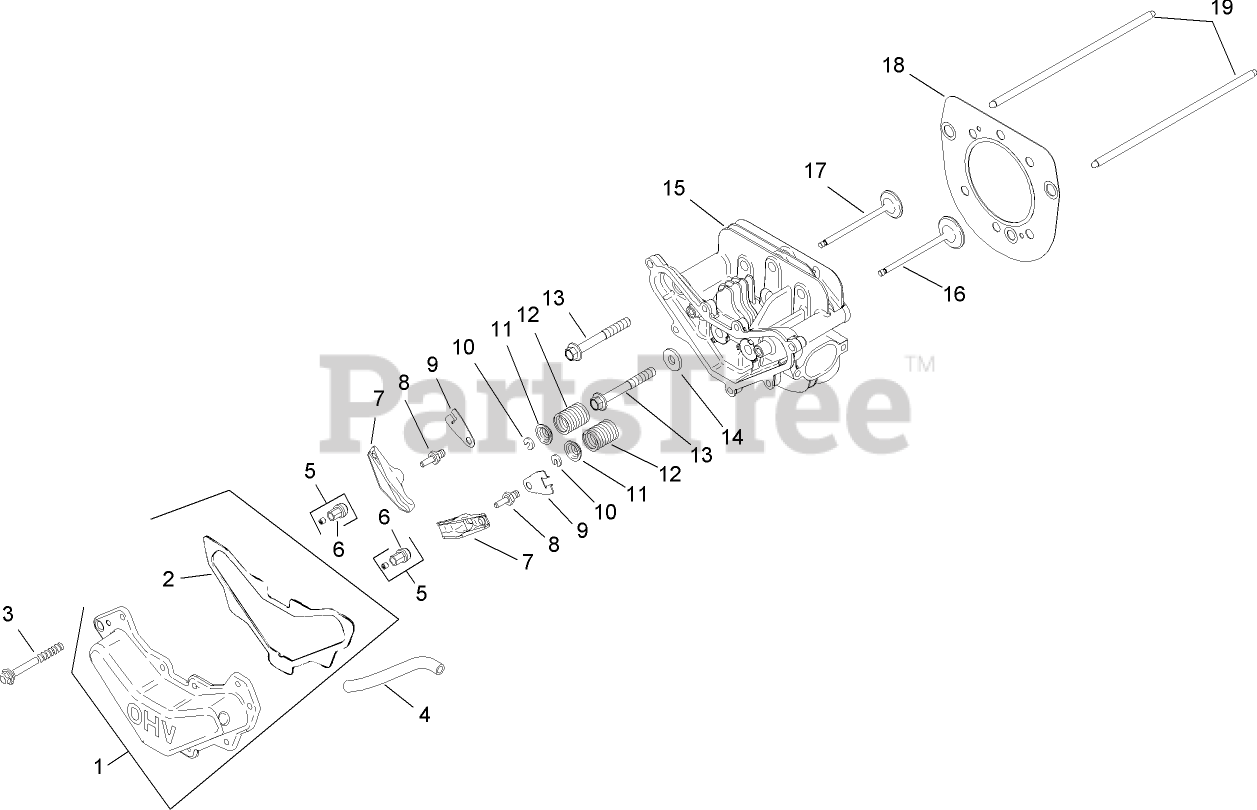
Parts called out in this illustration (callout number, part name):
1	Valve Cover Kit (Includes 2)
2	Gasket-Cover, Valve
3	SCREW-HHFTF (M6X1.0X20)
4	Hose-Breather
5	Screw-Set
6	Pivot-Arm, Rocker
7	Arm-Rocker
8	Stud-Rocker
9	Plate-Guide, Push Rod
10	Lock-Retainer
11	Cap-Spring, Valve
12	Spring-Valve
13	Screw-Flange, Hex (M10x1.5x37)
14	Washer-Flat (1/2)
15	Head-Cylinder
16	Valve-Exhaust
17	Valve-Intake
18	Cylinder Head Gasket Kit (Includes 13-14, and Part Nos. 12 041 01-S, 12 041 02-S and 20 041 07-S)
19	Rod-Push
